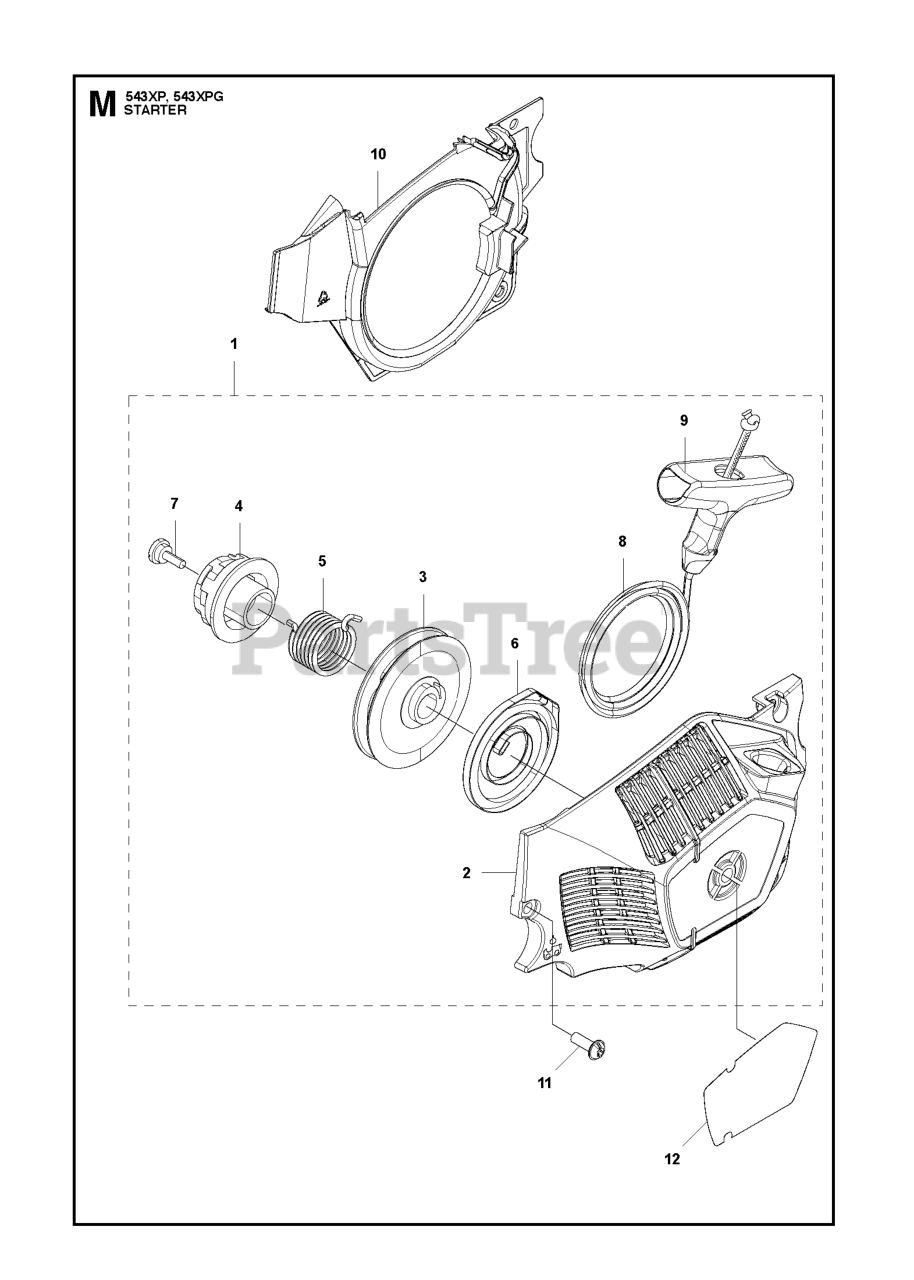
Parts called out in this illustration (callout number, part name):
1	STARTER ASSY XC25
1	STARTER ASSY
2	CASE COMP XC25
2	Covers
3	REEL
4	STARTER PULLEY CAM
6	SPRING CASSETTE ASSY OLD P/N
10	AIR CONDUCTOR COOLING
10	AIR BAFFLE
11	SCREW M5 X 14
12	DECAL
